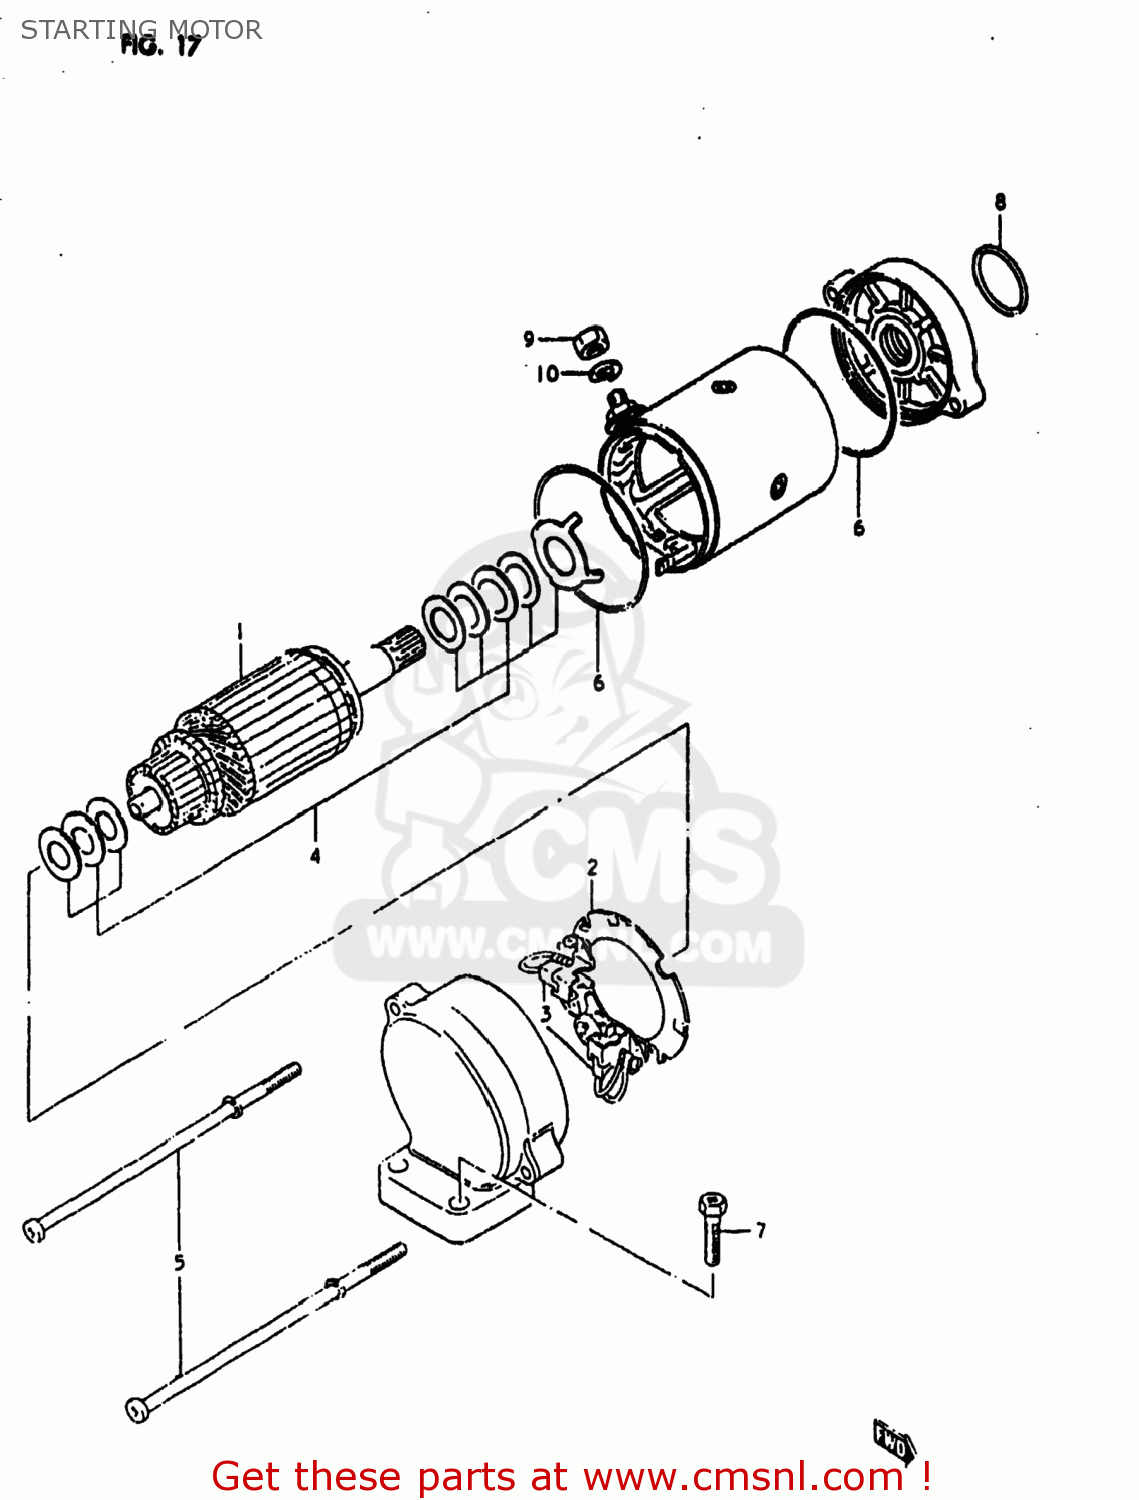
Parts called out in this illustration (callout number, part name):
1	ARMATURE
2	HOLDER ASSY
3	BRUSH SET
4	SHIM SET
5	BOLT,STARTING MOTOR HOUSING
6	O RING
7	SCREW (6X25)
8	O RING(D:2,ID:24.5)
9	NUT 6MM
10	LOCK WASHER
